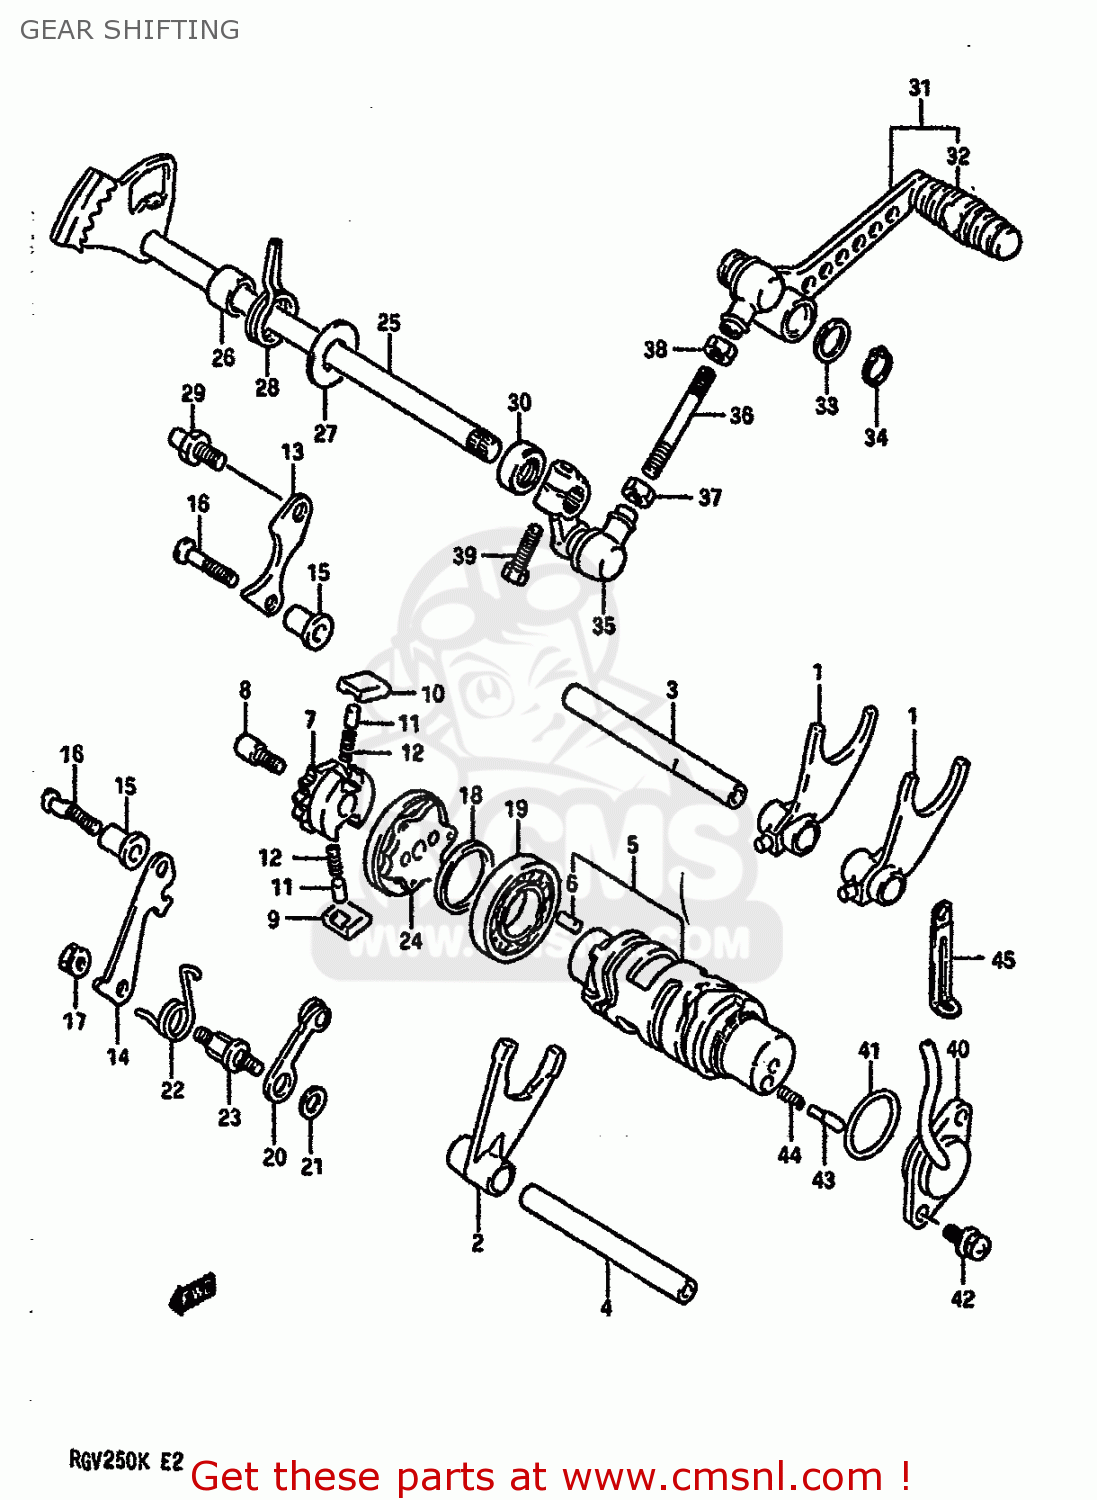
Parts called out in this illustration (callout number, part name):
1	FORK,GEAR SHIFT NO.1
2	FORK,GEAR SHIFT NO.3
3	SHAFT,GEAR SHIFT FORK(L:109)
4	SHAFT,GEAR SHIFT FORK
5	CAM,GEAR SHIFT
6	PIN
7	GEAR,GEARSHIFT CAM DRIVE
8	PIN,SHIFT CAM DRIVEN GEAR
9	PAWL,GEAR SHIFT NO.1
10	PAWL,GEAR SHIFT NO.2
11	PIN(5X8)
12	SPRING
13	LIFTER,GEAR SHIFT POLE
14	GUIDE,GEAR SHIFT CAM
15	SPACER(6.1X10X16)
16	SCREW
17	NUT
18	WASHER(25X32X3)
19	BEARING
20	STOPPER,SHIFT CAM
21	WASHER
22	SPRING, STOPPE
23	SUPPORT,CAM STOPPER ARM
24	PLATE,GEAR SHIFT CAM
25	SHAFT,GEAR SHIFT
26	SPACER(12X20X13.8)
27	WASHER
28	SPRING
29	STOPPER,GEAR SHIFT ARM
30	OIL SEAL
31	LEVER ASSY,GEAR SHIFT
32	RUBBER,GEAR SHIFT PEDAL
33	WASHER(12.5X20X1)
34	CIRCLIP
35	ARM,GEAR SHIFT
36	ROD,GEAR SHIFT LINK
37	NUT 6MM
38	NUT
39	BOLT
40	BASE ASSY,NEUTRAL SWITCH
41	O-RING (D:2.4 ID:26.2)
42	SCREW
43	PIN(5X15.5)
44	SPRING
45	CLAMP L:35
